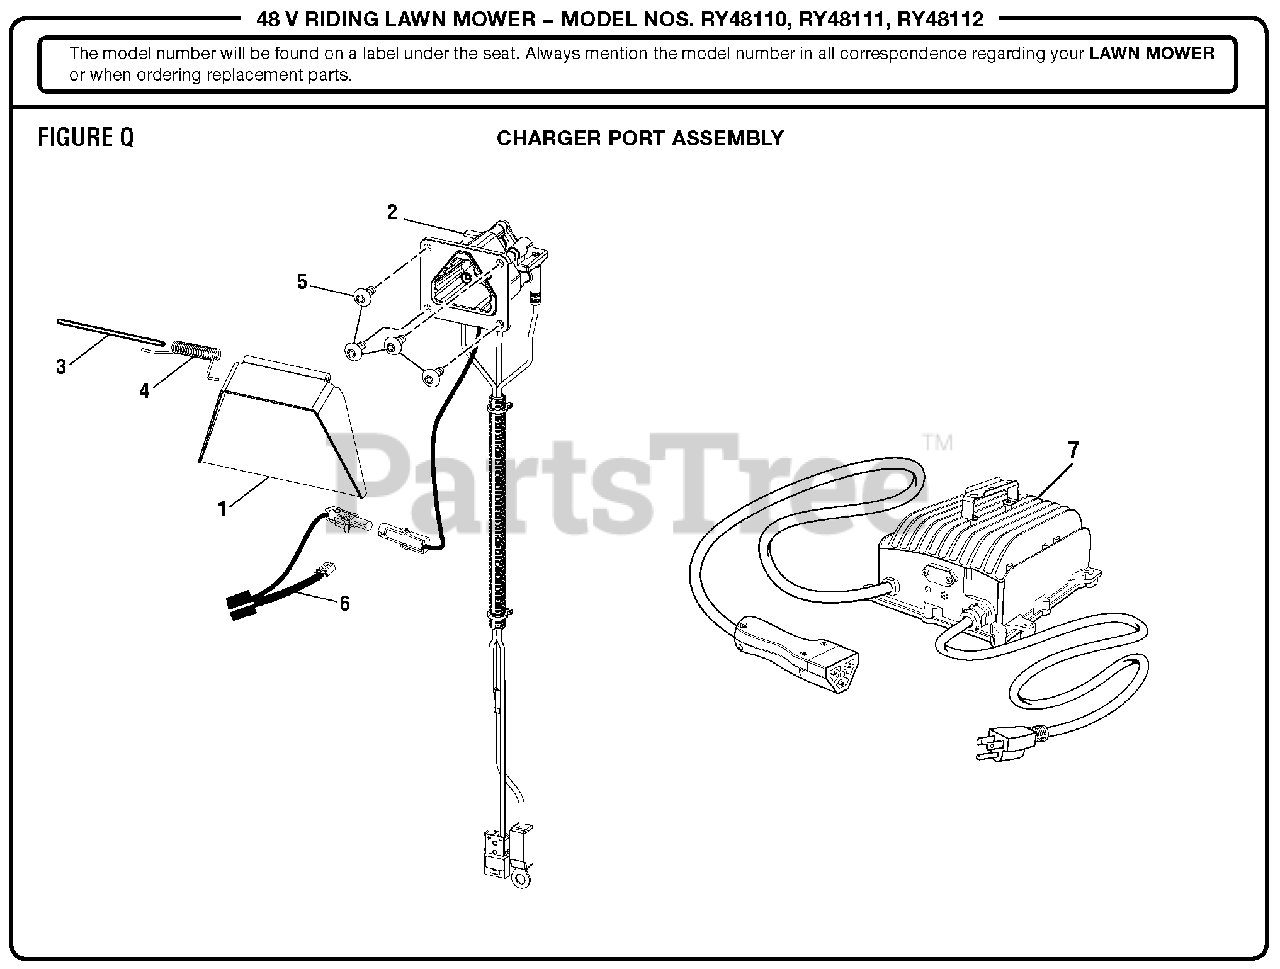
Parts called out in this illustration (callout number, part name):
1	Charger Port Hinge Door
2	Charger Receptacle
3	Hinge Pin
4	Torsion Spring
5	Screw (M6 x 16 mm, Torx Soc. Hd.)
6	Charger Lockout Circuit
